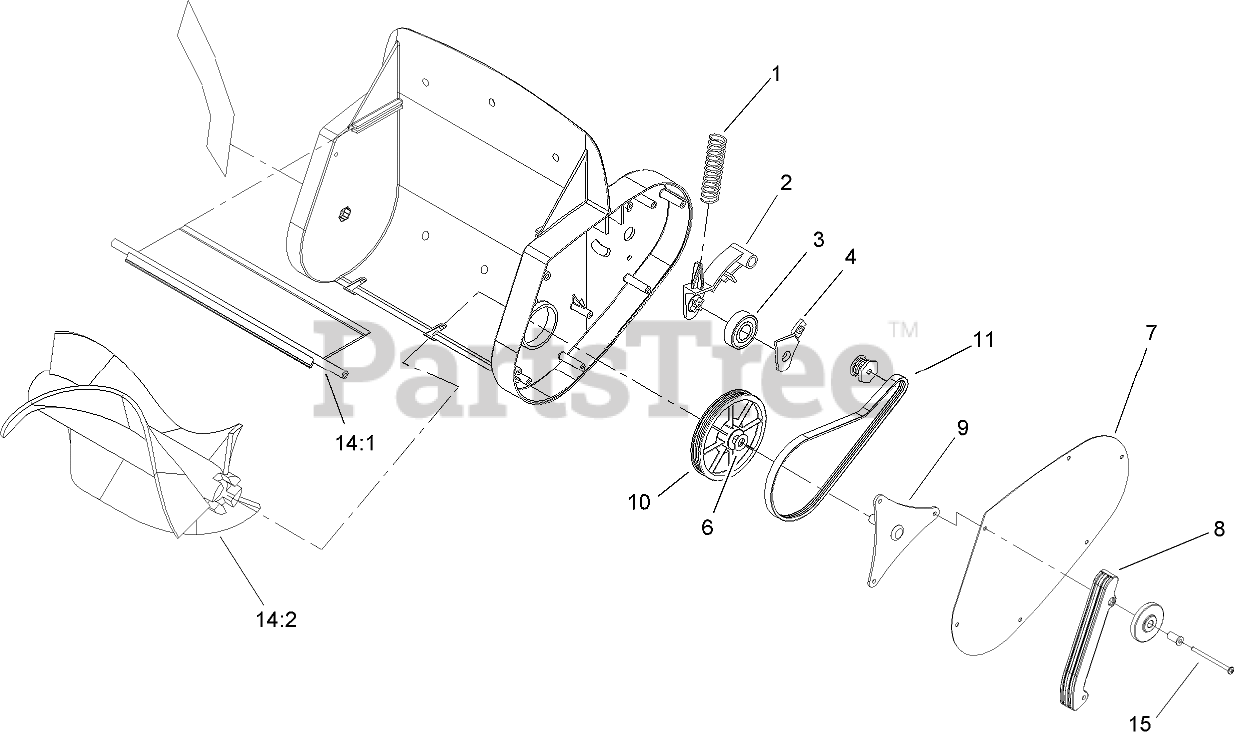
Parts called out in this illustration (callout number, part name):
1	SPRING
2	ARM-IDLER
3	BEARING-BALL
4	RETAINER-PULLEY, IDLER ARM
6	WASHER-THRUST
7	PLATE-SIDE
8	SCRAPER-LEFT, SWEEP
9	PULLEY BRACKET ASM
10	PULLEY ASM
11	BELT-DRIVE
14	LOOSE PARTS ASM
14:1	DEFLECTOR AND DECAL ASM
14:2	BRUSH-ROTOR
15	SCREW-PPH
